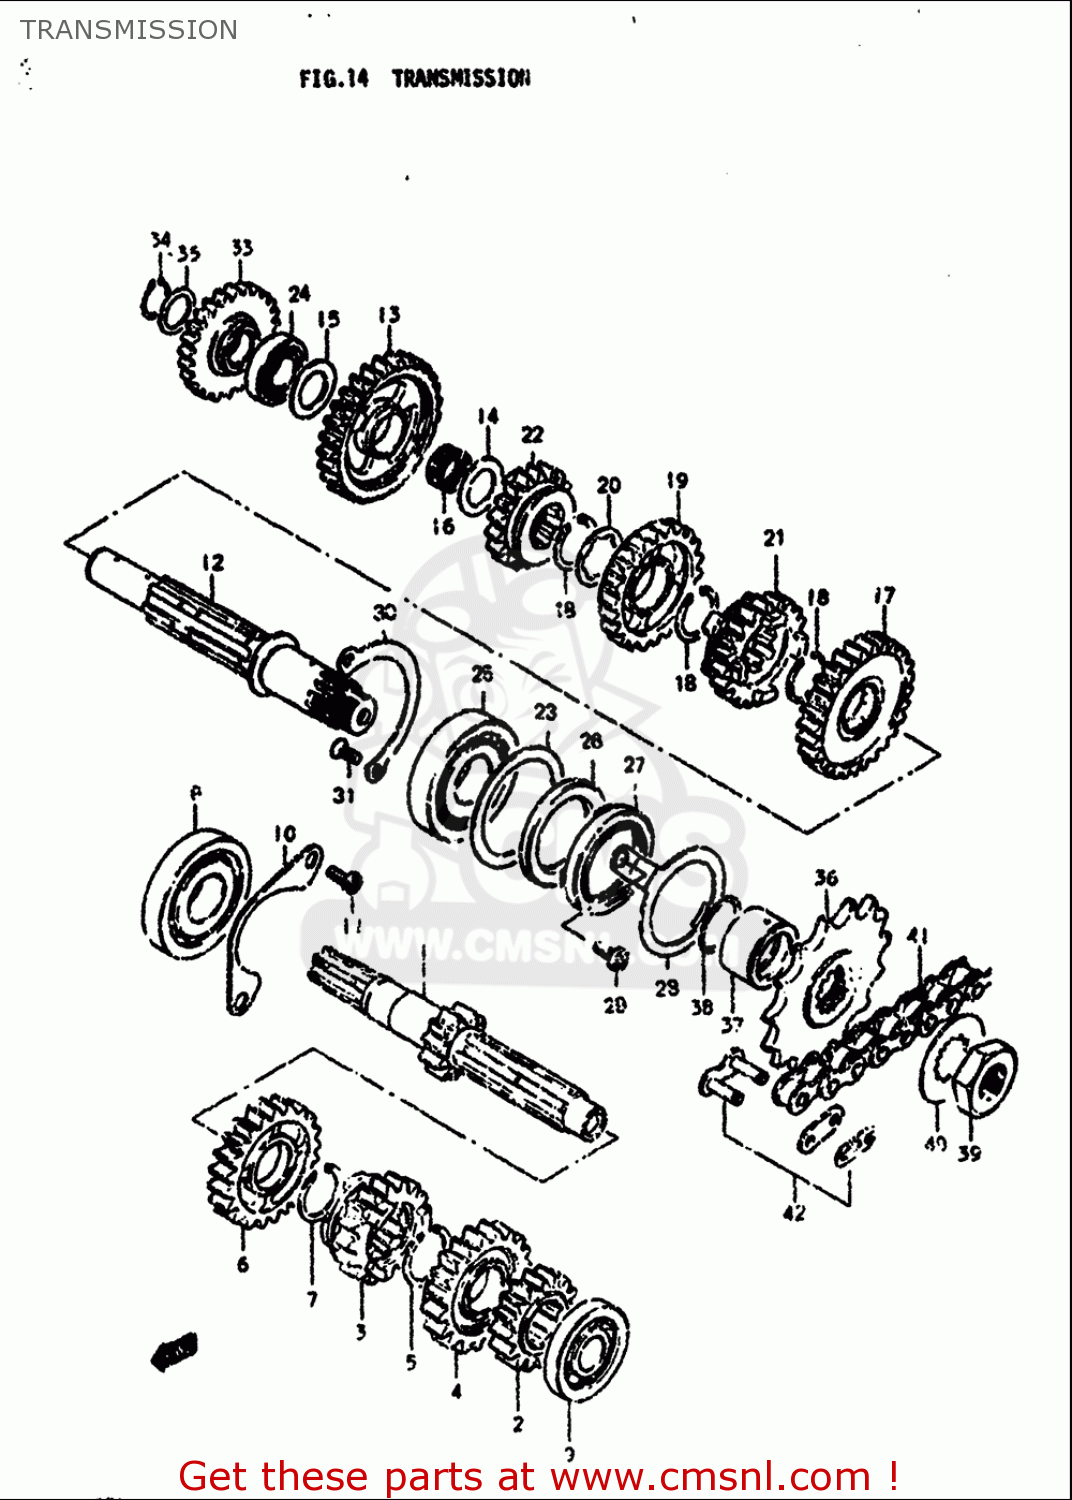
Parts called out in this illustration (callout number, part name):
4	GEAR,4TH DRIVE(NT:20)
5	CIRCLIP
6	GEAR,5TH DRIVE(NT:22)
7	CIRCLIP
8	BEARING(22X56X16)
9	BEARING(17X40X12)
11	SCREW
12	SHAFT,DRIVE
13	GEAR,1ST DRIVEN(NT:29)
14	SHIM(17X28X1)
15	WASHER
16	BEARING(17X21X9.8)
18	CIRCLIP
20	WASHER,LOCK
23	WASHER
24	BEARING(17X36X12)
25	BEARING(22X56X16)
26	OIL SEAL (30X47X5)
27	SEAL,OIL(30X47X7)
29	SCREW
31	SCREW
33	GEAR,KICK STARTER IDLER(NT:25)
34	CIRCLIP
35	WASHER
36	SPROCKET,ENGINE(NT:15)
38	O RING(D:2.5,ID:21)
39	NUT
40	WASHER,LOCK
41	CHAIN ASSEMBLY,DRIVE
42	JOINT,CHAIN
